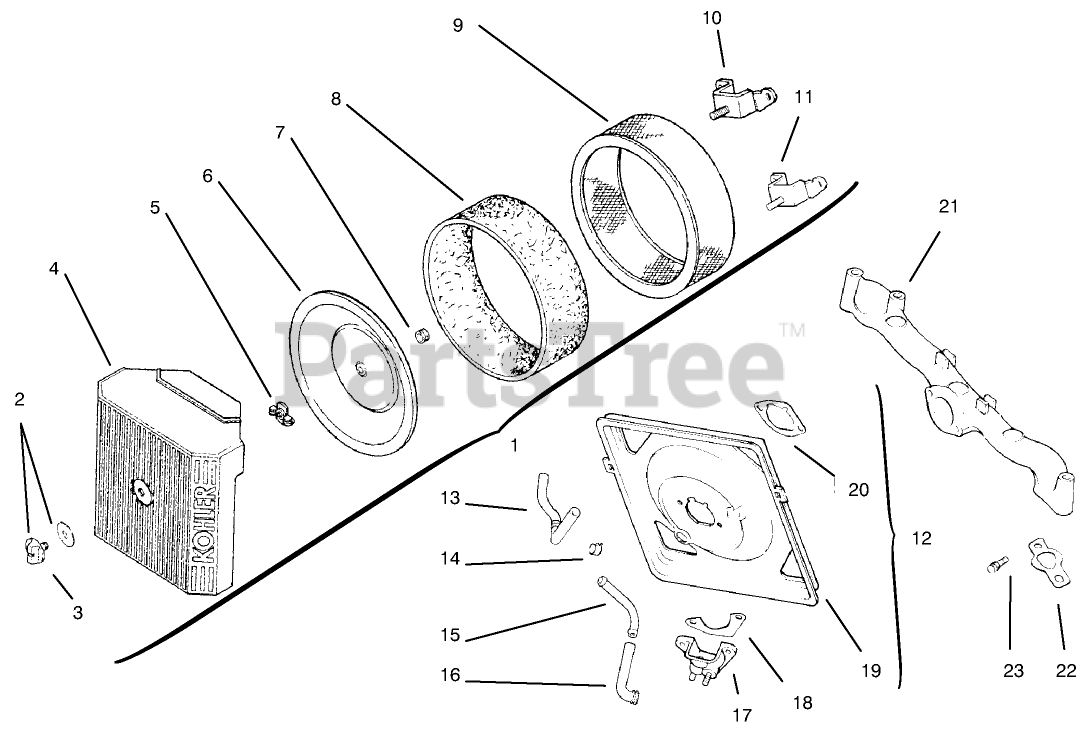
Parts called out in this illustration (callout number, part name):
1	Kit-A/C Cover INCL 2-4 (Only On: 72103;
2	Spring-Latch (Only On: 72103)
3	Latch-Lever (Only On: 72103)
4	Pin-Latch Lever (Only On: 72103)
5	Nut-Wing
6	Seal-Air Intake (Only On: 72103)
7	Cover-Inner Air Cleaner
8	Element-Precleaner
9	Element-Air Cleaner
10	Cup-Fuel Spitback (Only On: 72103)
11	Gasket-Fuel Spitback Cup (Only On: 72103, 72083)
12	Base-Air Cleaner (Only On: 72103)
13	Gasket-A/C Base (Only On: 72103, 72083)
14	Manifold-Intake (Only On: 72103)
15	Gasket-Intake Manifold
